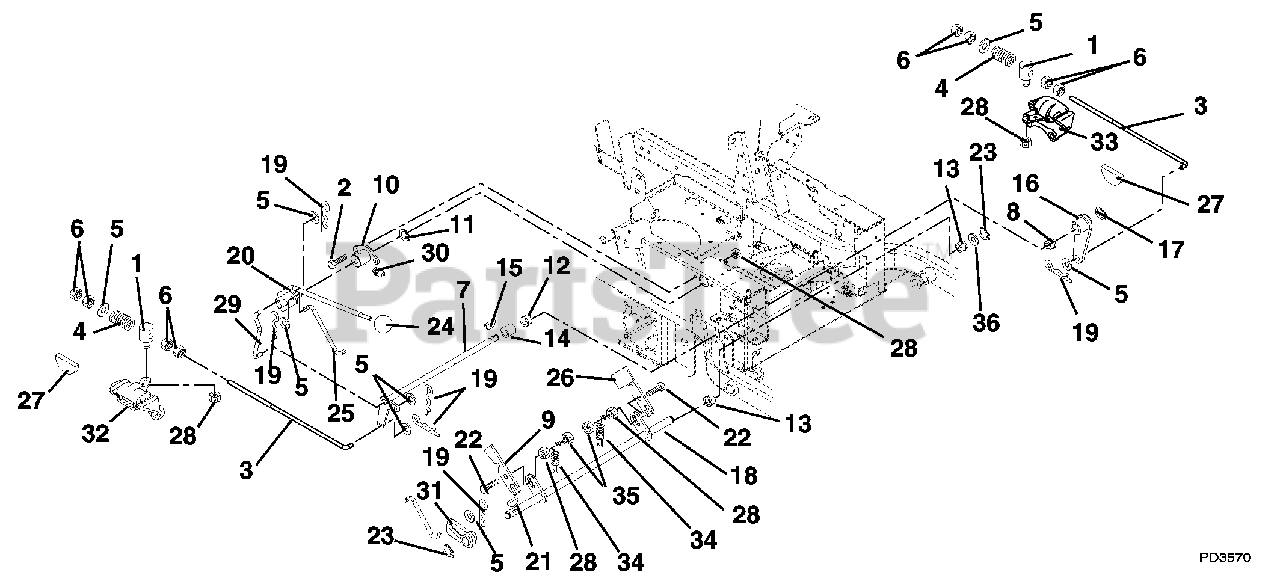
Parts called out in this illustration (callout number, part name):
1	Pivot, Brake Rod
2	Bolt, Hex .31-18 x .75 Grade 5
3	PTO Link Rod
4	Spring, Compression .143 x .710 x 2.00
5	Washer, Flat Steel .406 x .812 x .065
6	Nut, Hex .38-16
7	Weldment, Brake Cross Shaft
8	Bushing, Flange Nylon .63 x 1.00 x .625
9	Slide, Interlocking Brake
10	Bushing, Flange
11	Ring, Retaining External .625 x .05
12	Bushing, Flange Nylon .762 x 1.00 x .58 x 1.48
13	Bushing, Flange .50 x .75 x .75 x 1.00
14	Bushing, Sleeve .75 X 1.00 X .75
15	Key, Woodruff .19 x .75 Hard #9
16	Arm, Brake - Left Hand
17	Ring, Retaining External .625 x .050
18	Weldment, Mechanical Brake
19	Pin, Hair
20	Weldment, Brake Actuating
21	Key, Woodruff .13 x .63
22	Bolt, Hex .31-18 x 1.25 Grade 5
23	Ring, Retaining External .50 x .05
24	Knob, Steering Lock
25	Linkage, Brake Actuating
26	Interlock, Safety Switch
27	Pad, Disk Brake
28	Nut, Locking Top Flange .31-18
29	Linkage, Brake Actuating
30	Fitting, Lube .25-28 x .256
31	Weldment, Parking Brake Hub
32	Brake, Right Hand Caliper
33	Brake, Left Hand Caliper
34	Spring, Tension .061 x .50 x 3.0
35	Nut, Locking Center .31-18
36	Washer, Flat Steel .505 x 1.00 x .062
